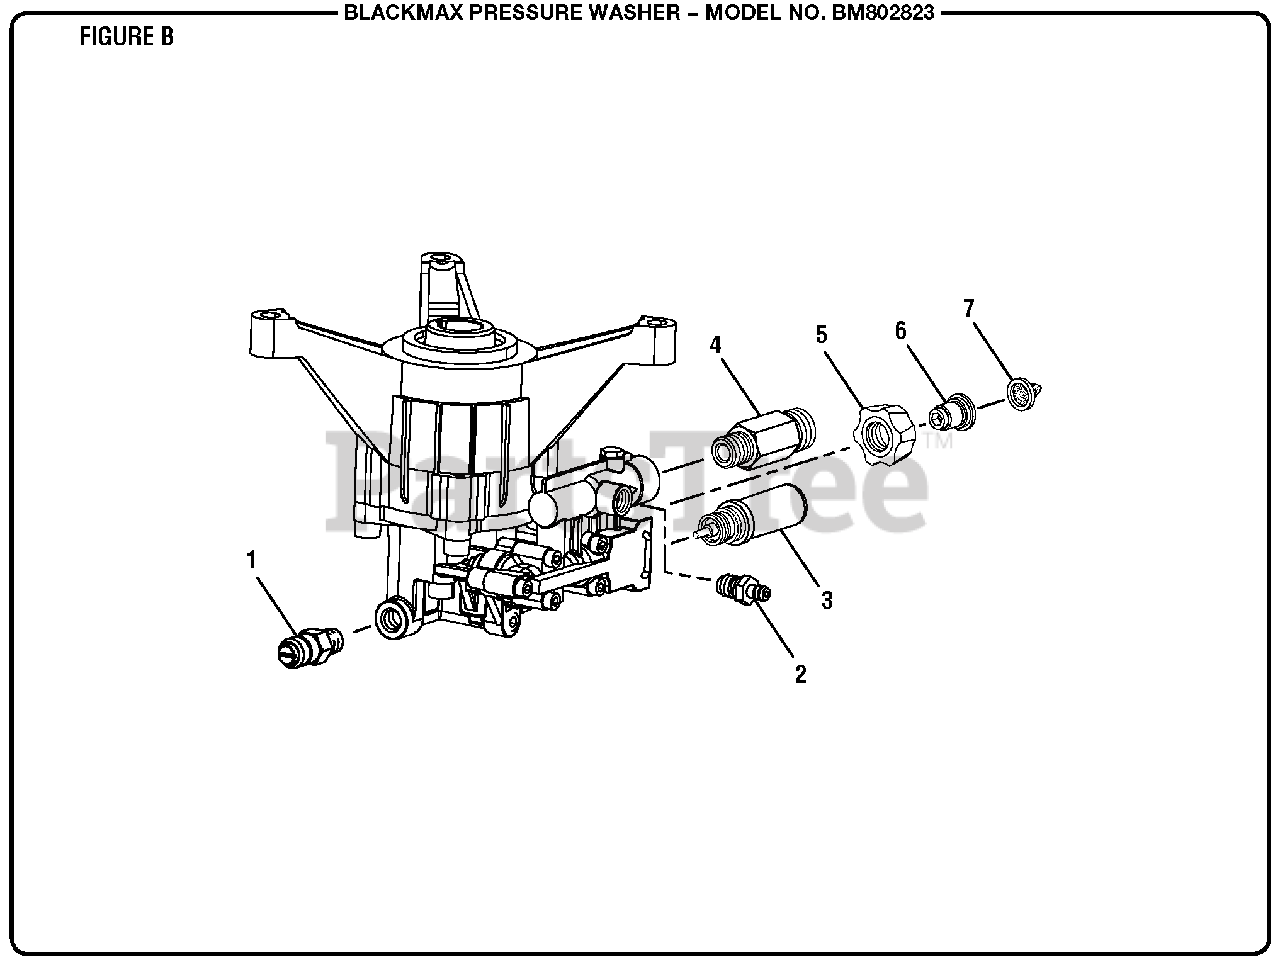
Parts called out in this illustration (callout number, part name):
1	Thermal Release Valve
2	Soap Injector Kit
3	Unloader Valve Assembly
4	Outlet Tube
5	Inlet Filter Adapter/Brass Insert
6	Inlet Filter Connector
7	Filter Screen
